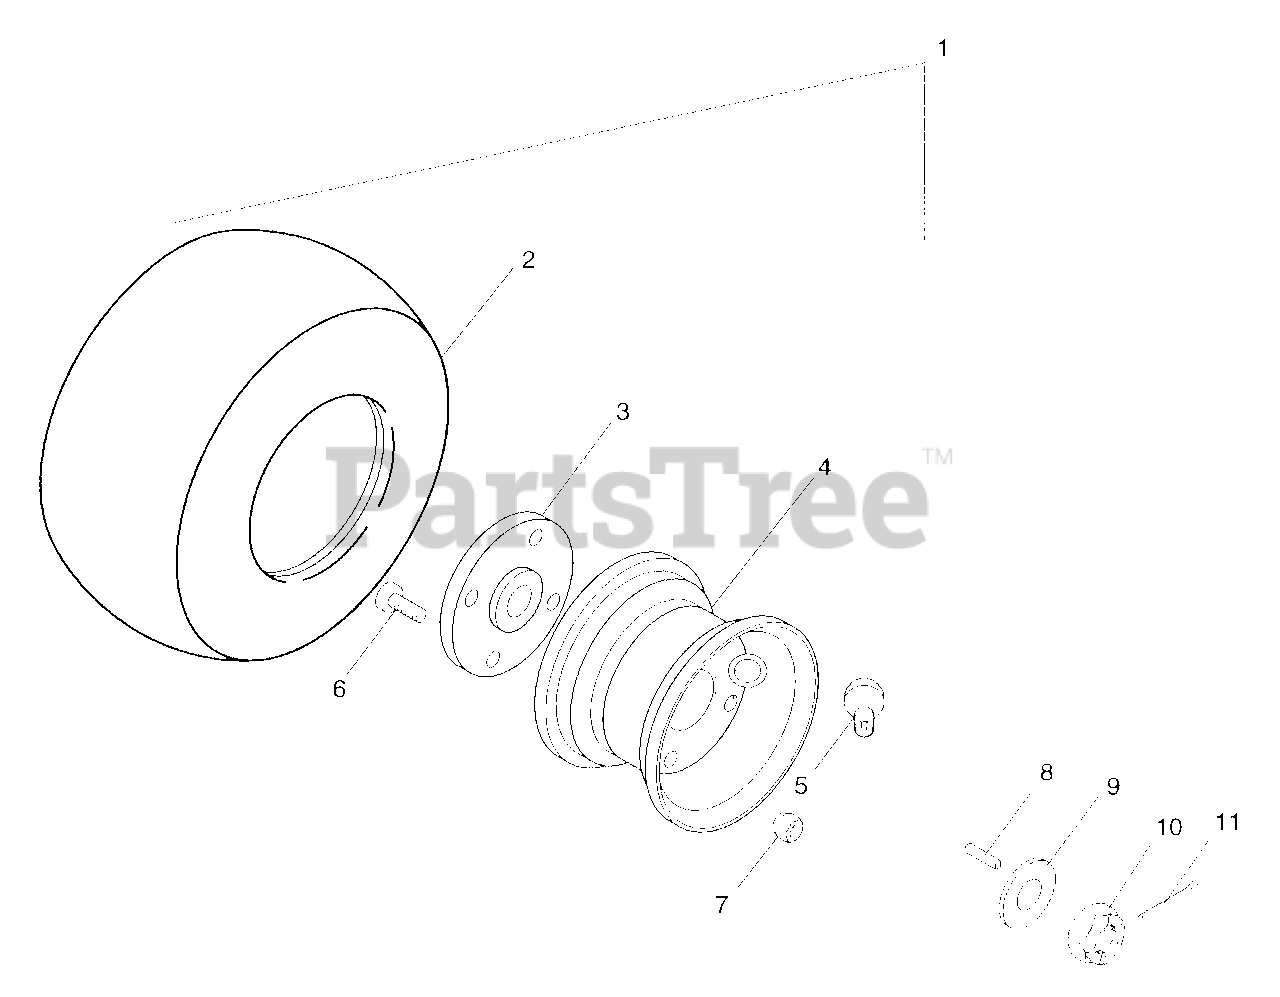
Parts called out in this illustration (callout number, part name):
1	Wheel Asm 18 x 8 - 50 - 8
2	T/Whl Assy 18 x 8.50 - 8
3	Asm, Hub
4	Asm, Rim
5	Valve Stem Ass'y
6	Bit, 1/2 - 20 x 1.25 Pan Hd
7	Nut - Hex .50 - 20
8	Key, Sq 3/16 x .750
9	Wshr - Fl - Stl .813 x 1.370 x .100
10	Nut, Hex 3/4 - 28 Slotted
11	Pin - Cotr .06 x 1.00
